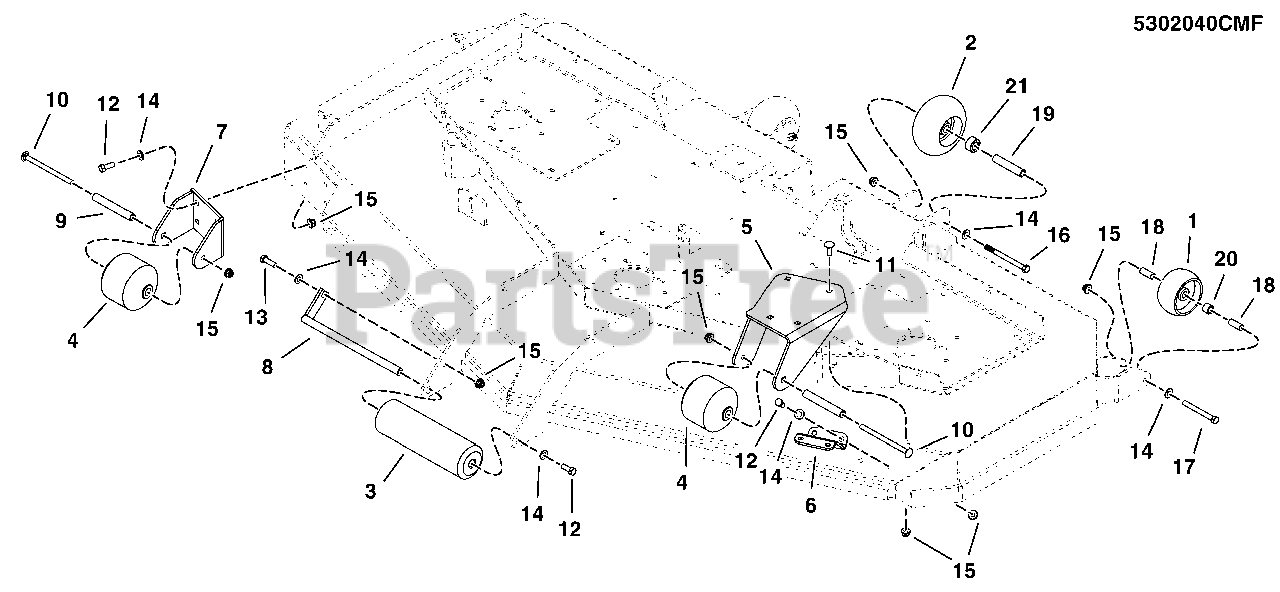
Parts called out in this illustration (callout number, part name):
1	WHEEL- 2.00 WIDE 3.88 DIA 0.531ID POLY
2	GAUGE WHEEL-2.70
3	ROLLER, DECK
4	ROLLER, SMALL
5	WELD, ANTI-SCALP BRACKET - RED
6	PLATE, ANTI-SCALP SUPPORT - RED
7	WELD, BRACKET, ANTI-SCALP - RED
8	WELD, BRACKET, ROLLER PIN - BLK
9	SPACER, .38 X .63 X 4.31
10	BOLT, 3/8-16 X 5-1/2, CARRIAGE
11	BOLT-RD HD SQ NK 3/8-16X1.000 G5 BLK
12	BOLT, 3/8-16 X 1 GD5 YZ
13	BOLT, 3/8-16 X 1-1/8 GD5 YZ
14	WASHER, 3/8 SAE
15	NUT, 3/8-16 HEX NYLOCK FLANGE
16	BOLT, 3/8-16 X 4-1/2 GD5 YZ
17	BOLT, 3/8-16 X 3-1/2 GD5 CZ
18	SPACER, .38 X .50 X 1.25
19	SPACER, .38 X .63 X 3.25, CZ
20	SPACER, .51 X .75 X .56, CZ
21	SPACER, .64 X 1.13 X .63, CZ
